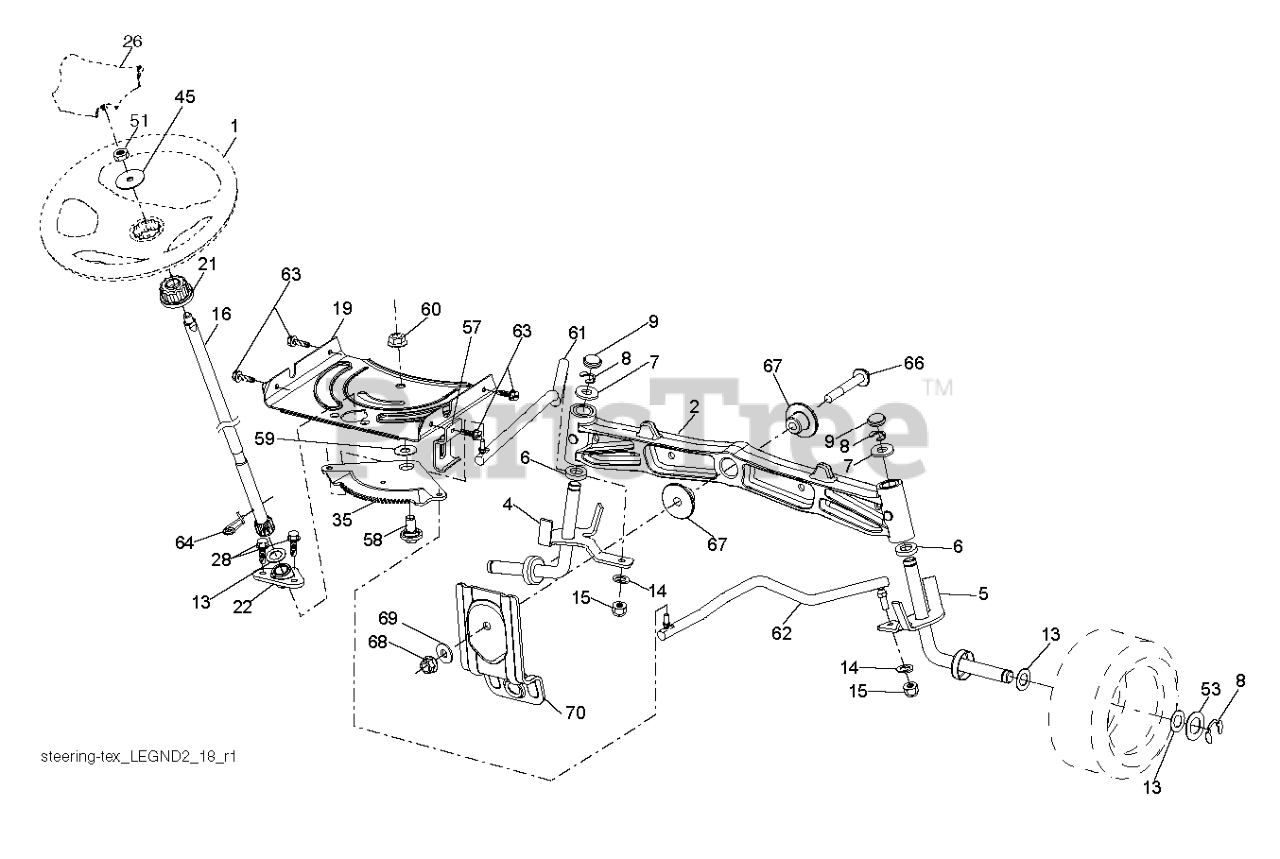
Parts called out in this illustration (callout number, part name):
1	WHEEL.STEERING.HUSQ.PREM.HRDRM
2	AXLE.CAST.IRON
4	SPINDLE.WELDED.LH.16"TEX
5	SPINDLE.WELDED.RH.16"TEX
6	THRUST WASHER
9	CAP.SPINDLE.BLACK
14	WASHER, LOCK 3/8
15	NUT CROWNLOCK 3/8-24
16	SHAFT, STEERING
19	PLATE.STEER.DDL.NLT/NG
21	ADAPTER, WHEEL STNG..
22	STEERING.SUPT.LOWER.
26	INSERT.CAP.WHL.STRG.HUSQ.PREM
28	SCREW, 3/8-16X3/4
35	GEAR.SECTOR.PLATE.DDL.
45	WASHER 9/16"ID, 2 3/8"OD
51	NUT.HEX.1/2-20
53	WASHER.HARDENED
57	BRKT.UPSTOP.GT/LT.TEX
58	BOLT.SHOULDER.SECTOR.P
59	WASHER.THURST.SECTOR.S
60	NUT FLANGE LOCK 5/8-11
61	DRAGLINK.LH.BALLSTUD.D
62	DRAGLINK.RH.BALLSTUD.D
63	SCREW
64	RETAINER.CLIP.SPRING.S
66	BOLT HEX FGHD 7/16-14 X 3 SERR
67	BUSHING.PM.FRONT AXLE
68	NUT.LOCK.FLANGE.7/16
69	WASHER.1.5X.505X.118
70	BRKT.DECK.SUSPENSION.F
